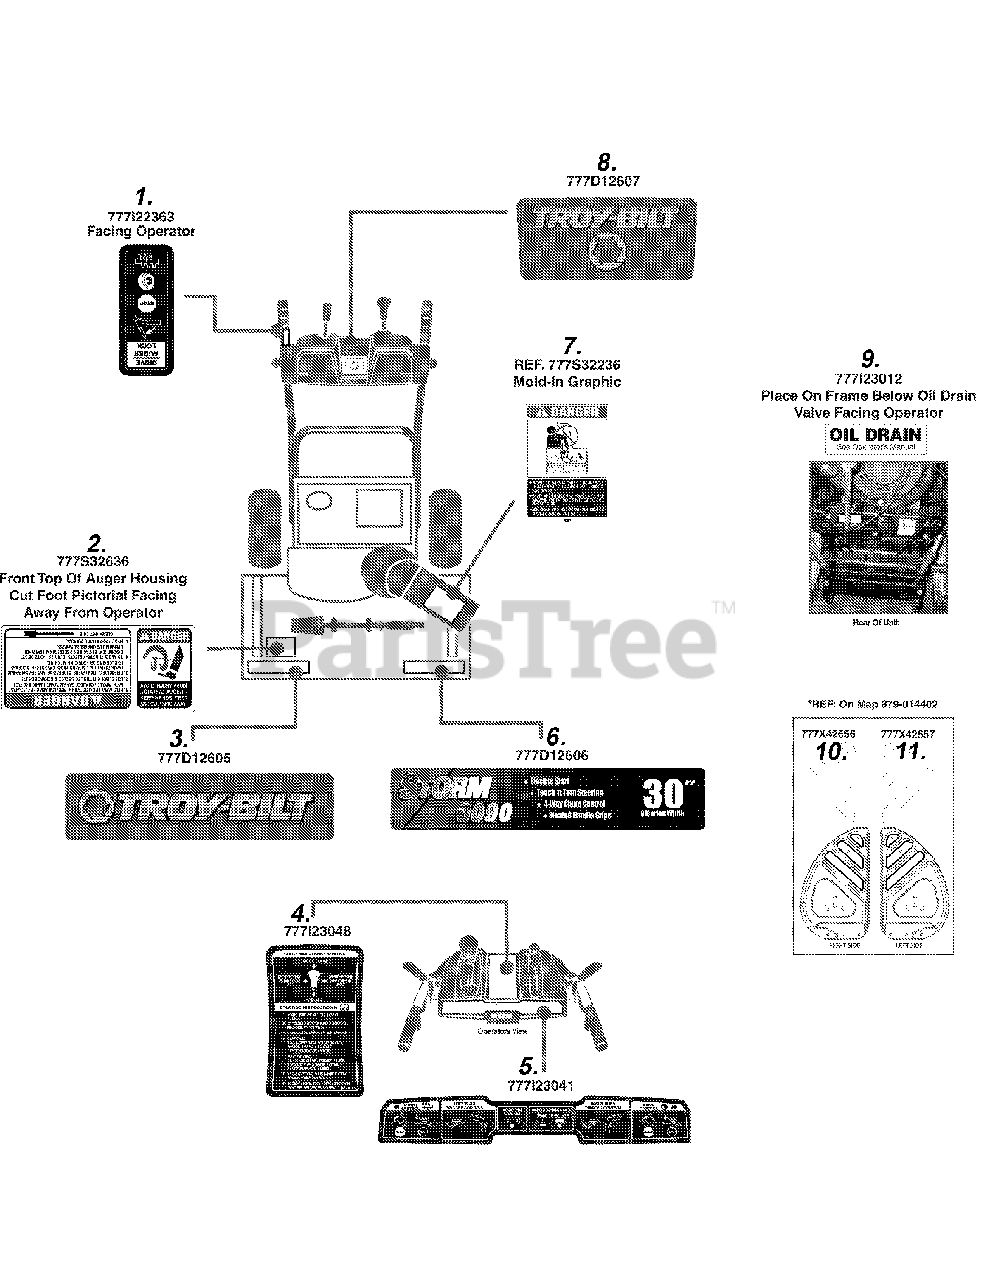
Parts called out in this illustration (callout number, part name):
1	LABEL-DRV/AUGR LOCK
2	LABEL-SNOW HOUSING
3	LABEL-SNOW FRONT LH AUGER TROY
4	LABEL-SNOW Q PANEL INSTRUCTION
5	LABEL-SNOW:P/Q PNL:STR:TBILT W/HH
6	LABEL-SNOW FRONT RH AUGER STORM
7	LABELSNOW CHUTE
8	LABEL-SNOW HANDLE 4 STYLE FRONT
9	LABEL-SNOW OIL DRAIN
10	LABEL-SNOW RH AUGER REFLECTOR
11	LABEL-SNOW LH AUGER REFLECTOR
